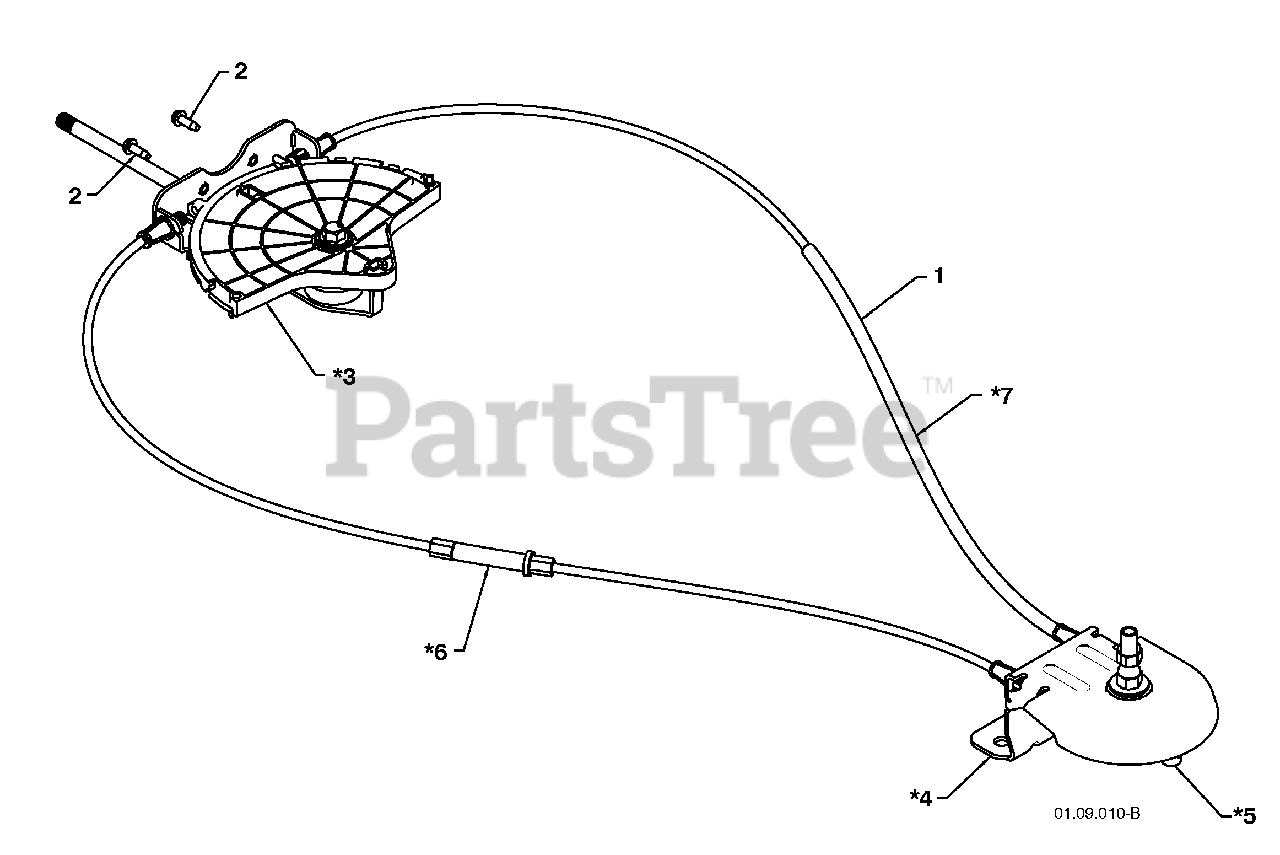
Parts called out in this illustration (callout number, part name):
1	LEVER/CABLE ROTATOR ASSEMBLY
2	SCREW 10-24 X .625
3	ROTATOR HEAD
4	ROTATOR PIVOT BRACKET
5	PULLEY PIVOT
6	CABLE ASSEMBLY ADJUSTABLE
7	CABLE ASSEMBLY HEAT SHIELD
